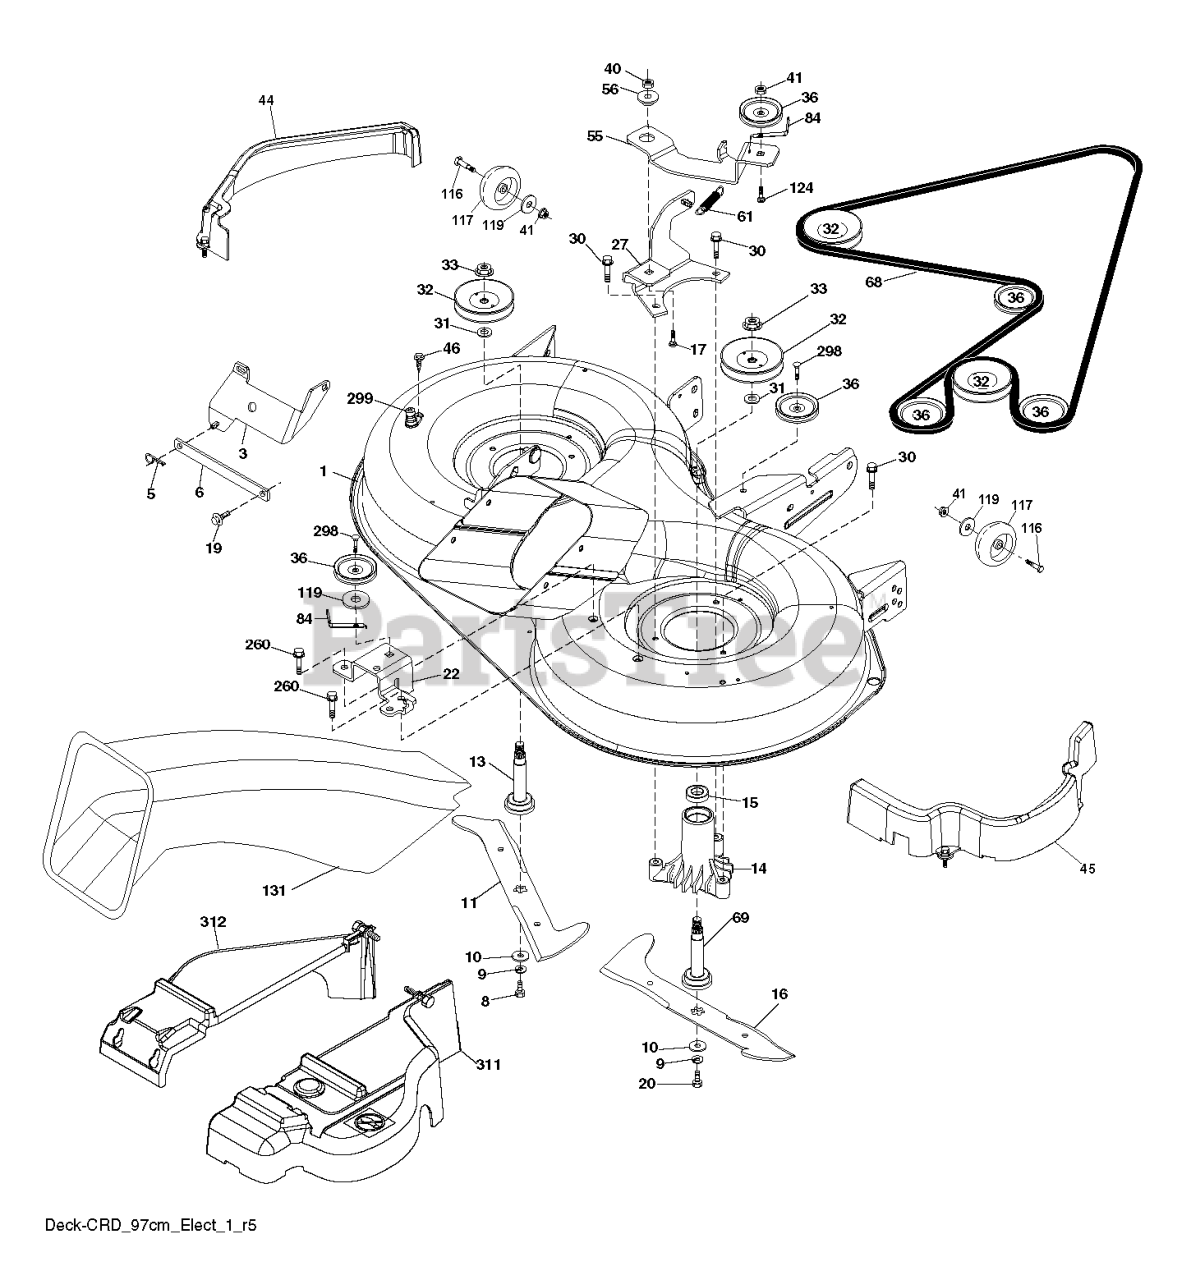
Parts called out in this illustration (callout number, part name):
1	DECK.WLDT.97.CRD.2GWB.
3	BRACKET.ASM.BAR.SWAY.CHASS
5	RETAINER-SPRNG RB
6	BAR.SWAY.92.CRD
8	BOLT.3/8-24X1.25 GR8
9	LOCKWASHER
10	WASHER.BLADE
11	BLADE.3N1.LH.CRD.97
13	SHAFT ASM VENT
14	HOUSING.MANDREL.VENTED (MACHD)
16	BLADE.3N1.RH.CRD.97
17	BOLT.3/8-14X1.25
19	BOLT SHD 5/16-18
20	BOLT.3/8-24X1.25GR8. LHTHRD
22	BRACKET.SUPT.IDLER.REAR.RH
27	BRACKET.ASM.SUSP.REAR.RH.
30	SCREW, WASHER HEAD
31	WASHER.SPACER.MANDREL
32	PULLEY MANDREL
33	NUT.FLANGE.LOCK.TOP
36	PULLEY.IDLER.4.25
41	NUT LOCK FLG 3/8-16 UNC
44	COVER MANDREL LEFT
45	COVER MANDREL RIGHT
46	SCREW.1/4-20X5/8
55	ARM.IDLER.92 CRD.2006
56	SPACER.RETAINER.MOWER
61	SPRING
68	BELT.DRIVE.CRD.97.2010
69	SHAFT.ASM.W/LWR.BRG.RH.THREAD
84	KEEPER, BELT IDLER
116	BOLT.SHOULDER.3/8-16X3-5/8.
117	RP WHEEL. GUAGE RALLY
119	WASHER
124	BOLT.3/8-16X1.50
131	CHUTE BAGGER
260	SCREW 3/8-16X1/2
298	SCREW LT
299	PORT.WASHOUT
311	COVER RIGHT
312	COVER LEFT
